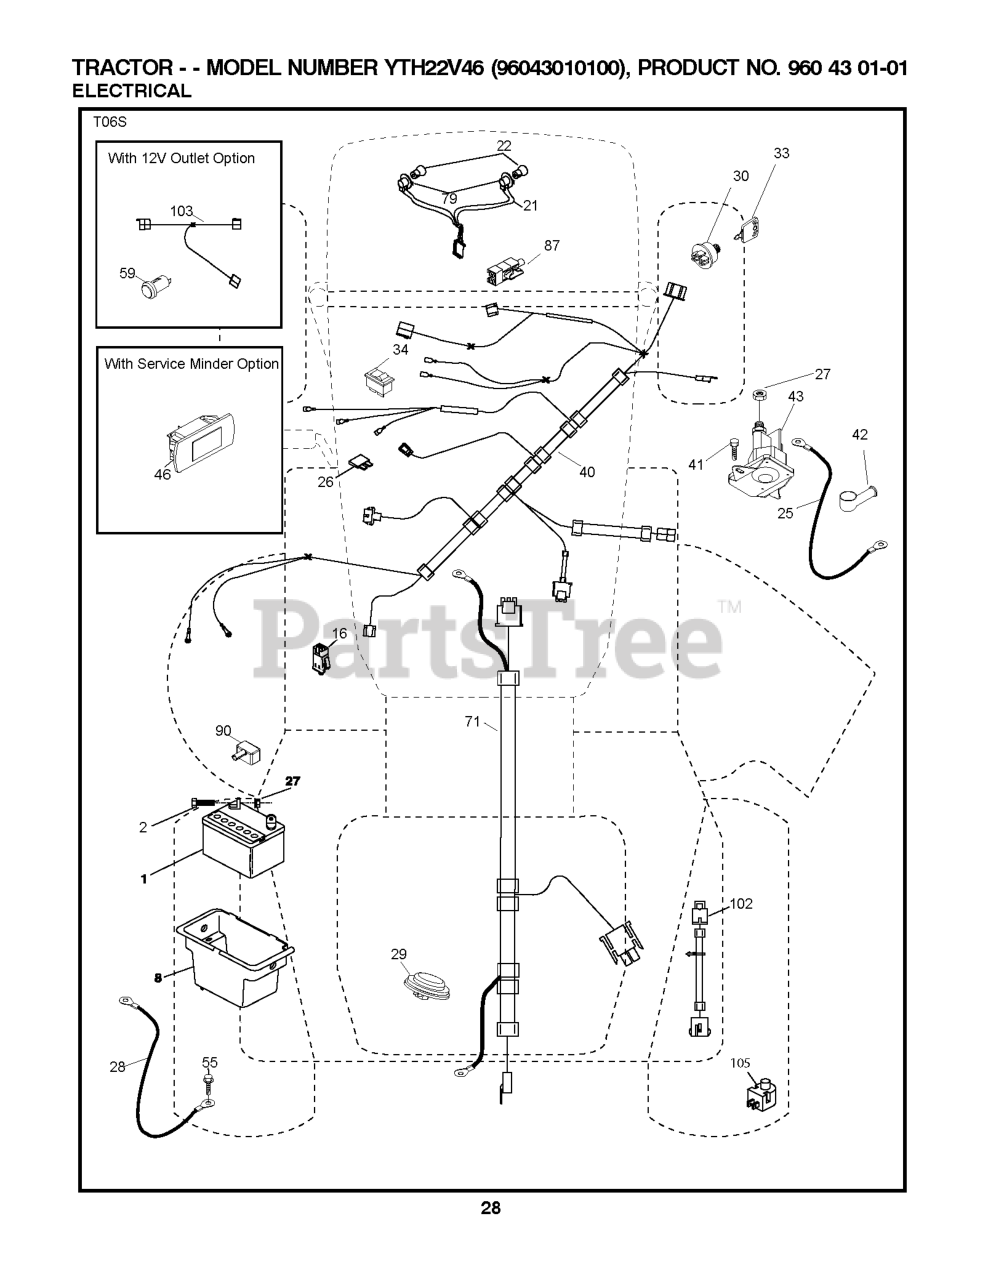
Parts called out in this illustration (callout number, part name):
1	Battery 12 Volt 25 Amp
2	BOLT.HEX.1/4.X.3/4.DICHROMATE
8	BOX.BATTERY.MNT.REAR.L
16	SWITCH INTERLOOK PUSH-IN
21	HARNESS ASSY LIGHT
25	CABLE.STARTER.6G.BL/RED.17.5
26	FUSE 20AMP
27	NUT
28	CABLE.BLACK.18"REAR.BA
29	SWITCH.SEAT.DELTA.OPC.
30	SWITCH.IGN.DELTA.W.LGH.ROS
33	KEY.CHAIN.BLISTER.PACK.GEN.USA
40	HARNESS IGN. DASH
41	SCREW
42	TERMINAL COVER
43	SOLENOID.W/BRASS.PLUNGER
46	RP.GUAGE.SRVCMNDR.HRMTR.
55	SCREW 5/16"
71	HARNESS.IGN.CHASS.TEX.REAR.BAT
79	BULB HOLDER ASM.
87	SWITCH.INTRLCK.CLUTCH.
90	COVER, TERMINAL BATTERY
102	HARNESS PIGTAIL PCH TEX ROS
105	REVERSE SWITCH
